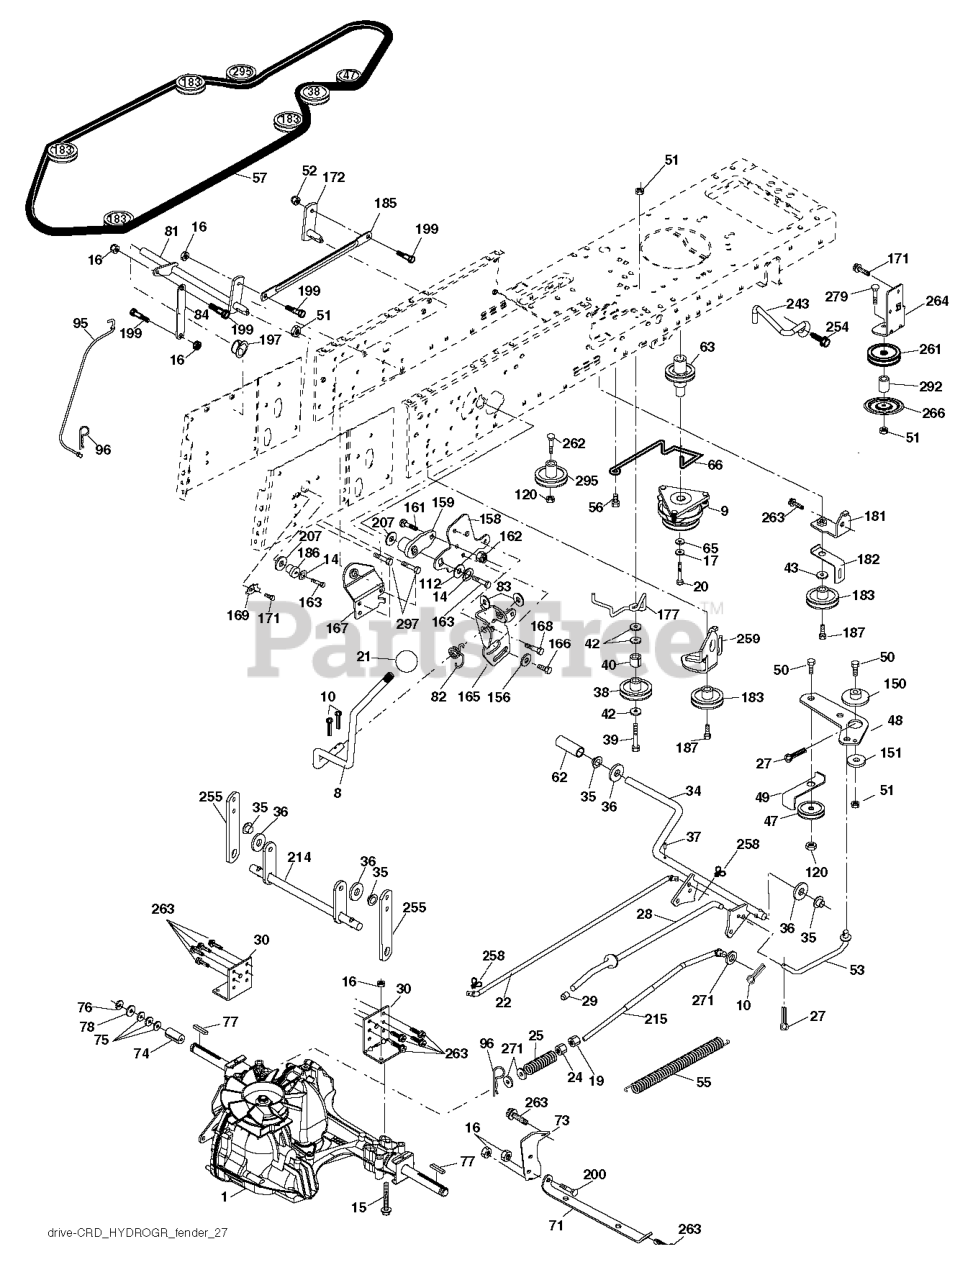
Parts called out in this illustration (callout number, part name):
8	ROD SHIFT FENDER ADJUST LT
9	CLUTCH.ELECTRIC.OGURA.EURO.
10	PIN COTTER
14	LOCKWASHER
15	BOLT HEX 5/16-18 GR 5
16	NUT.71038.31-18.HEX.NYLOCK
19	NUT
20	BOLT HEX 7/16-20X4-1/4"
21	KNOB.DUCKHEAD.1/2
22	ROD
24	NUT
25	SPRING BRAKE ROD
27	COTTER PIN
28	ROD, PARKING BRAKE
29	CAP
30	BRKT, TRNSXLE MNT 20"
34	SHAFT, FOOT PEDAL
35	BEARING.NYLON
37	DRIVE PIN
38	PULLEY.FLAT
42	WASHER
47	IDLER PULLEY
48	BELLCRANK, CLUTCH
49	RETAIN BELT
50	BOLT.3/8-16X1.50
52	LOCKNUT
53	LINK.CLUTCH.7.66.2005
55	SPRING, RETURN LT
56	SCREW.3/8-16
57	V-BELT 113"
62	PEDAL COVER T
63	PULLEY.ENGINE.CVX.LT
65	LOCKWASHER
66	KEEPER BELT ENGINE
71	STRAP TORQUE LH HYDRO
73	STRAP TORQUE RH HYDRO
74	SPACER AXLE
77	SQUARE KEY
81	ASM.CROSS.SHAFT.REAR.CRD.0510
82	SHIFT SPRING
83	WASHER
84	LINK.PNT.TRANSAXLE.0510.CRD
95	LINK
96	RETAINER M
120	NUT LOCK FLG 3/8-16 UNC
150	BUSHING.BELLCRANK.GRD.DR
151	WASHER 12/32X2X10GA
156	WASHER.SRRTD.5/16
158	BRACKET.SHIFT.MOUNT
159	RB HUB.SHIFT
161	BOLT
162	NUT.CROWNLOCK.1/4
165	BRACKET.PIVOT.LEVER
166	CAPSCREW.HXHD.FLG.5/16-18X.625
167	BRACKET.SUPT.SHIFT.CRD
168	BOLT.SHOULDER.5/16-18X
169	PLATE.FASTENING.CROSS.SHAFT
172	LINK
181	BRACKET
182	BELT GUIDE
183	PULLEY.V-IDLER.
185	LINK
186	HUB.TAPERED.ROUND.CRD
187	BOLT.5/16-18X1.25
197	NYLINER SNAP 5/8" ID
199	BOLT SHOULDER 5/16-18 UNC
207	WASHER NYL
214	LEVER
215	ROD
243	BRACKET, ANTI-ROTATION
254	SCREW 3/8-16X1
255	SHAFT
258	CLIP RETAINER
259	BRACKET
261	FLAT IDLER PULLEY
263	SCREW, 3/8-16X3/4
264	BRACKET.IDLER
266	PROTECTOR
271	WASHER
292	SPACER
295	PULLEY IDLER COMPOSITE
297	SCREW LT.3/8-46X5/8
